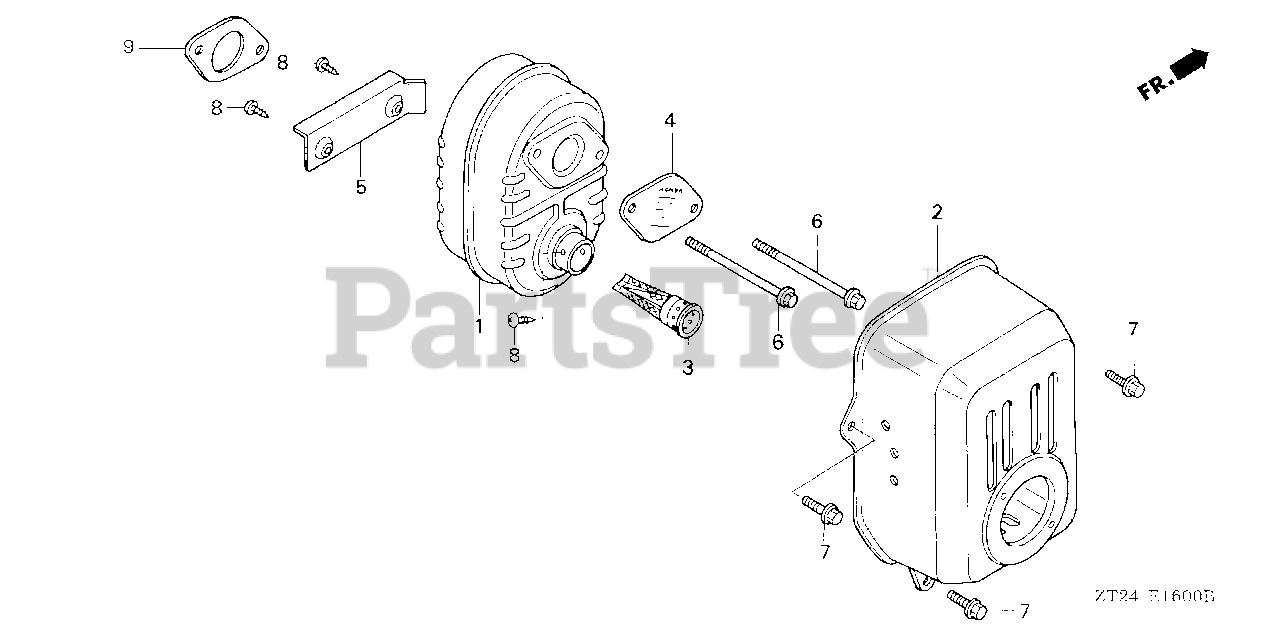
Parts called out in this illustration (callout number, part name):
2	PROTECTOR, MUFFLER
3	ARRESTER, SPARK
4	PLATE, ARRESTER NUMBER
5	SHROUD, MUFFLER
6	BOLT, FLANGE (6X79) (CT200)
7	BOLT, FLANGE (6X12) (CT200)
8	SCREW, TAPPING (4X6)
9	GASKET, MUFFLER
